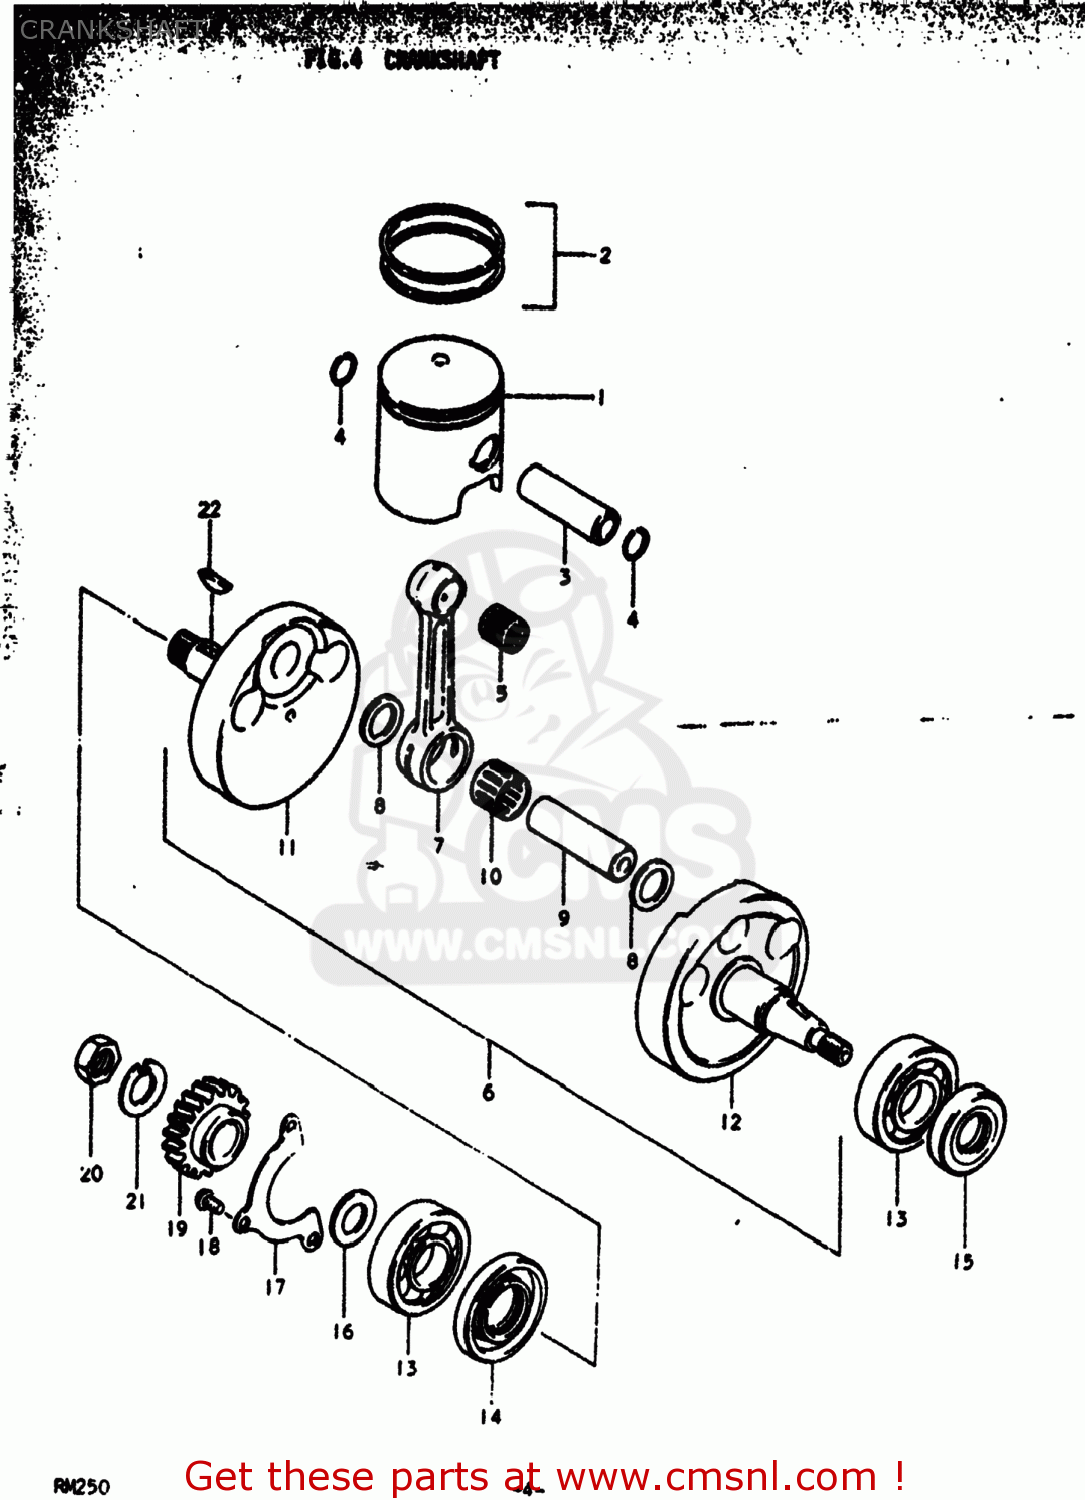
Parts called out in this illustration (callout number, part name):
1	PISTON
2	RING SET,PISTON
3	PIN,PISTON (18MM)
4	CIRCLIP
5	BEARING(18X23X22)
6	CRANKSHAFT ASSEMBLY
7	CONNECTING ROD
8	WASHER(24X29X1.5)
9	PIN,CRANK
10	BEARING
11	CRANKSHAFT
12	CRANKSHAFT,LEFT
13	BEARING
14	SEAL,OIL(35X62X9)
15	SEAL,OIL(24X50X9)
16	WASHER(20X48X1)
17	PLATE
18	SCREW 6X12
19	GEAR,PRIMARY DRIVE
20	NUT
21	WASHER
22	KEY
